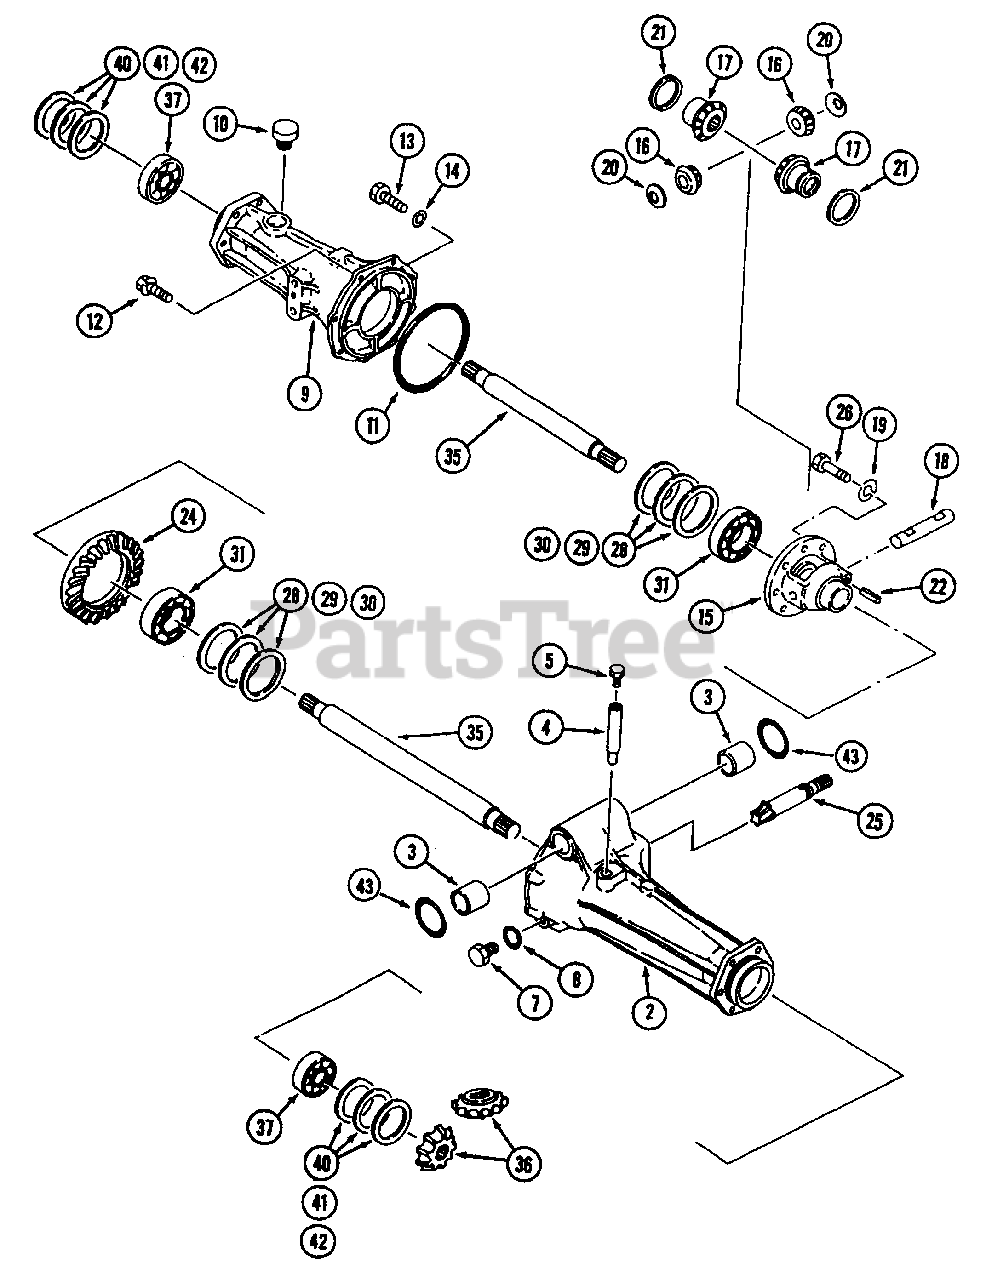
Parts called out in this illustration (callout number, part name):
2	Housing, Axle A
8	Washer, Seal
9	Case B, Center
18	Shaft, Pinion
20	Washer, Thrust
21	Washer, Thrust
24	Gear,Ring
25	Shaft, Pinion
